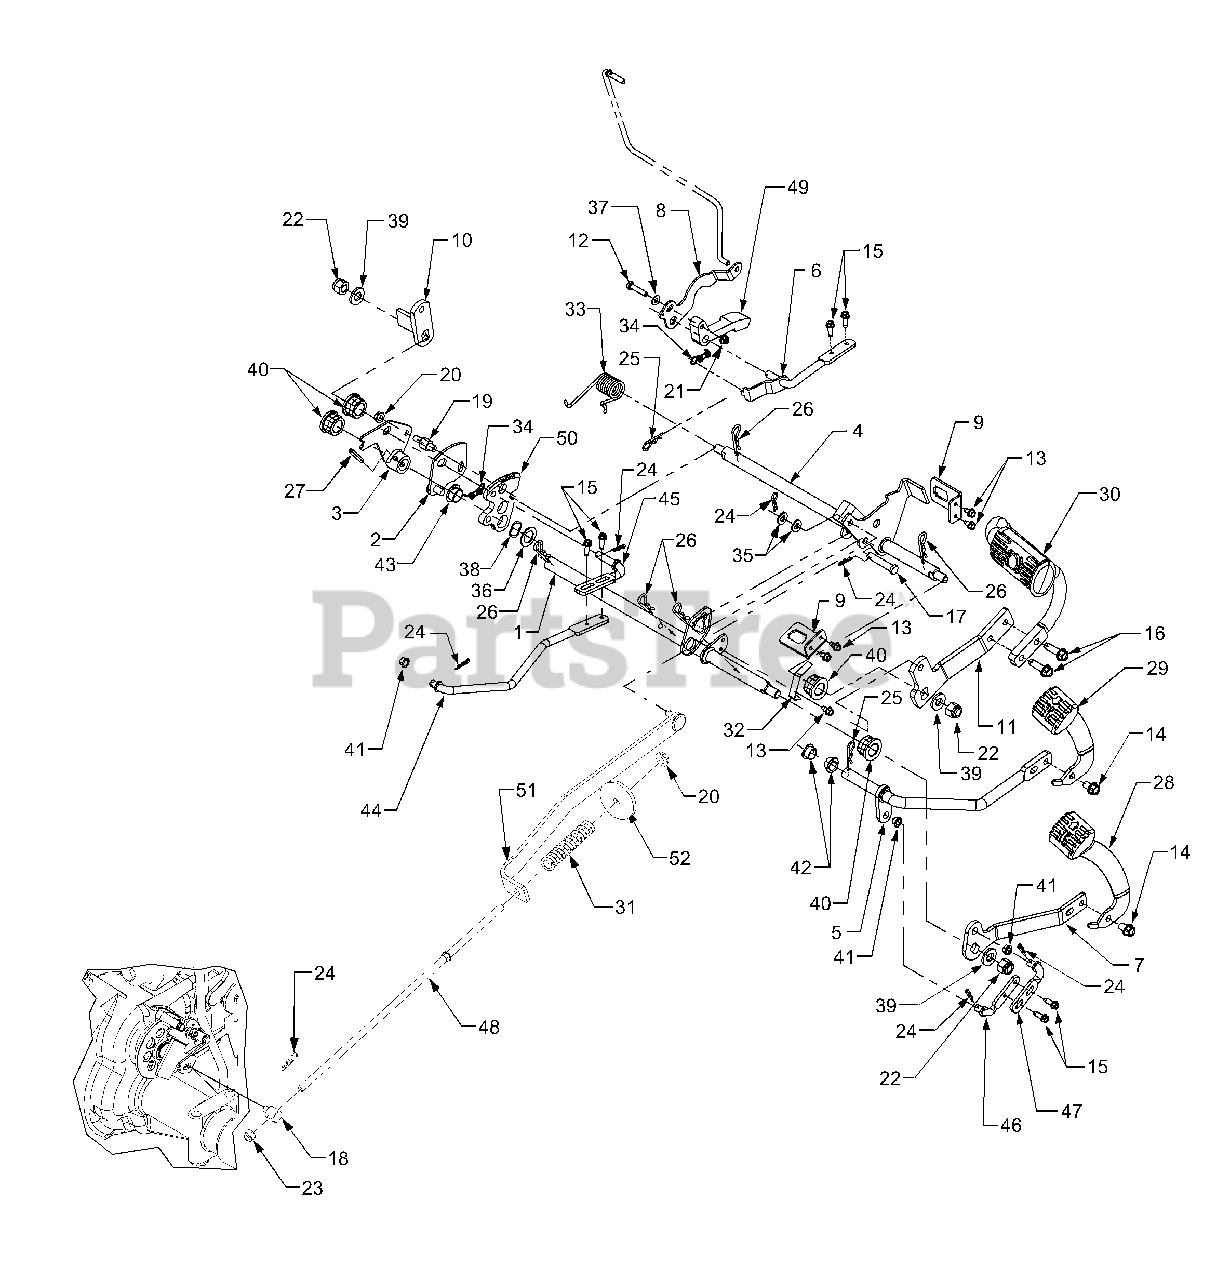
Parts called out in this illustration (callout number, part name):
1	Shaft Assembly, Pedal
2	Plate, Disengagement
4	Shaft Assembly, Brake
5	Shaft Assembly, Reverse
6	Rod Assembly, Cruise
7	Link, Pedal Mounting
8	Bracket, Rod Adjust
9	Bracket, Switch
10	Lever, Brake Diff Lock
11	Link, Brake Pedal
12	Screw, Hex Cap, 1/4-20 x 1.25 GR5
13	Screw, Hex Wash. Hd. Tapp 1/4-20 x .5
14	Screw, Hex Wash. Hd. Tapp 3/8-16 x .75
15	Screw, Hex Wash. Hd. Tapp 1/4-20 x .75
16	Screw, Hex Wash. Hd. Tapp 3/8-16 x 1.25
17	Pin, Clevis, 3/8 x 2.015
18	Ferrule, Adjust
19	Stud, Actuator
20	Nut, Hex Flange Lock, 5/16-18
21	Nut, Hex Flange Lock, 1/4-20
22	Nut, Hex Insert Lock, 1/2-20
23	Nut, Hex Insert Lock, 5/16-18
24	Pin, Internal Cotter
25	Pin, Internal Cotter
26	Pin, Internal Cotter
27	Pin, Spiral Spring, .25 x 1.5
28	Pedal, Forward
29	Pedal, Reverse
30	Pedal, Brake
31	Spring, Compression
32	Spring, No Cut Reverse
33	Spring, Torsion
34	Spring, Extension, .380 OD x 1.44
35	Washer, Flat, .344 x .688 x .065
36	Washer, Flat, .79 x 1.24 x .060
37	Washer, Flat, .25 x .62
38	Washer, Wave, .785 x 1.0 x .012
39	Washer, Flat, .531 x 1.06 x .134
40	Bearing, Hex Flange
41	Bearing, Flange
42	Bearing, Flange
43	Bearing, Flange
44	Rod, Rear Control
45	Rod, Front Control
46	Rod, Rear Connecting
47	Rod, Front Connecting
48	Rod, Brake
49	Cruise Latch
50	Plate, Cruise
51	Link Assembly, Brake
52	Washer, Flat, .341 x 2.25 x .10
